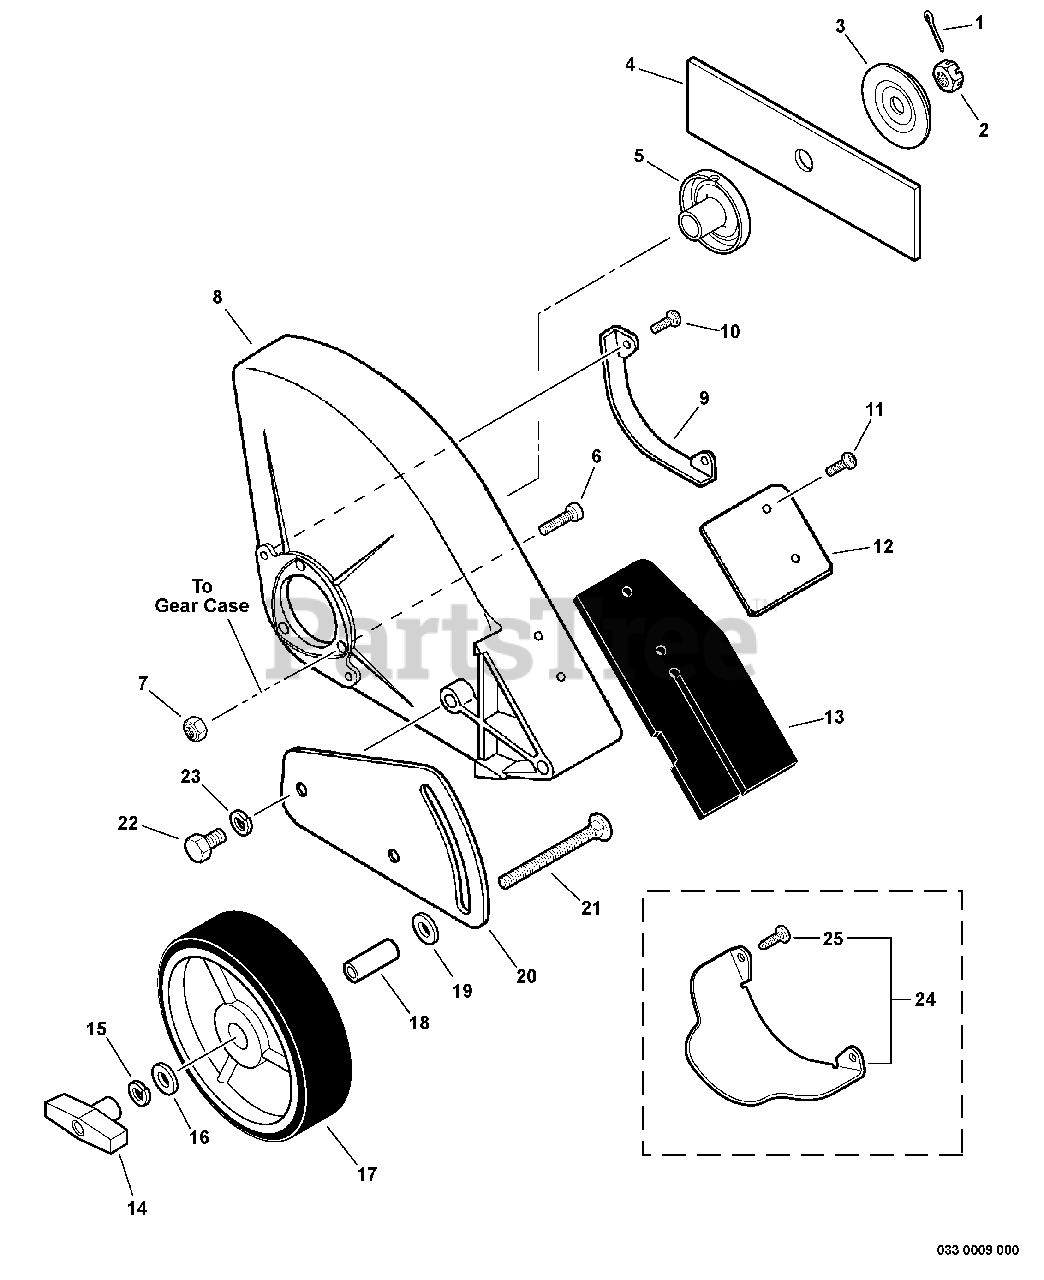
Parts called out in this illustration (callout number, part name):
1	PIN, SPLIT - 2X22
2	LOCKNUT - LEFT HAND
3	ADAPTOR, BLADE - LOWER
4	BLADE, EDGER
5	ADAPTOR, BLADE - UPPER
6	SCREW - 5X20
7	LOCKNUT - 5
8	SHIELD, BLADE
10	SCREW - 4X12
11	SCREW - 4X12
12	PLATE, FLAP
13	FLAP, DEBRIS
14	WINGNUT - 5/16-18
15	LOCKWASHER - 8
16	WASHER - 8
17	WHEEL - 6X1.5
18	COLLAR - 12
19	WASHER - 10
20	BRACKET, WHEEL
21	BOLT - CARRIAGE
22	BOLT - 8X14
23	LOCKWASHER - 8
24	SHIELD GUARD KIT
25	SCREW - 4X12 -- TAPPING
